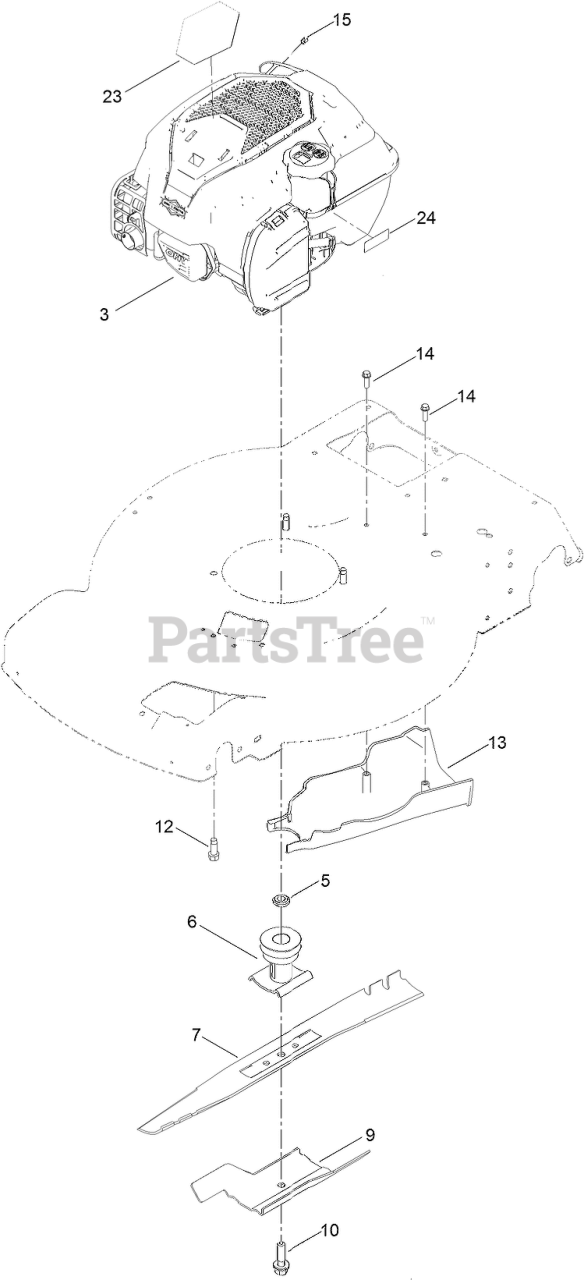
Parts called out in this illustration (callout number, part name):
5	SPACER-DRIVER
6	DRIVER-BLADE
9	ACCELERATOR-BLADE
10	BOLT-BLADE
12	SCREW-TAPTITE
13	COVER-BELT, REAR
14	SCREW-PLASTITE, HWH
15	STOP-ROPE
23	DECAL-SHROUD
24	DECAL-LEVEL, FUEL
